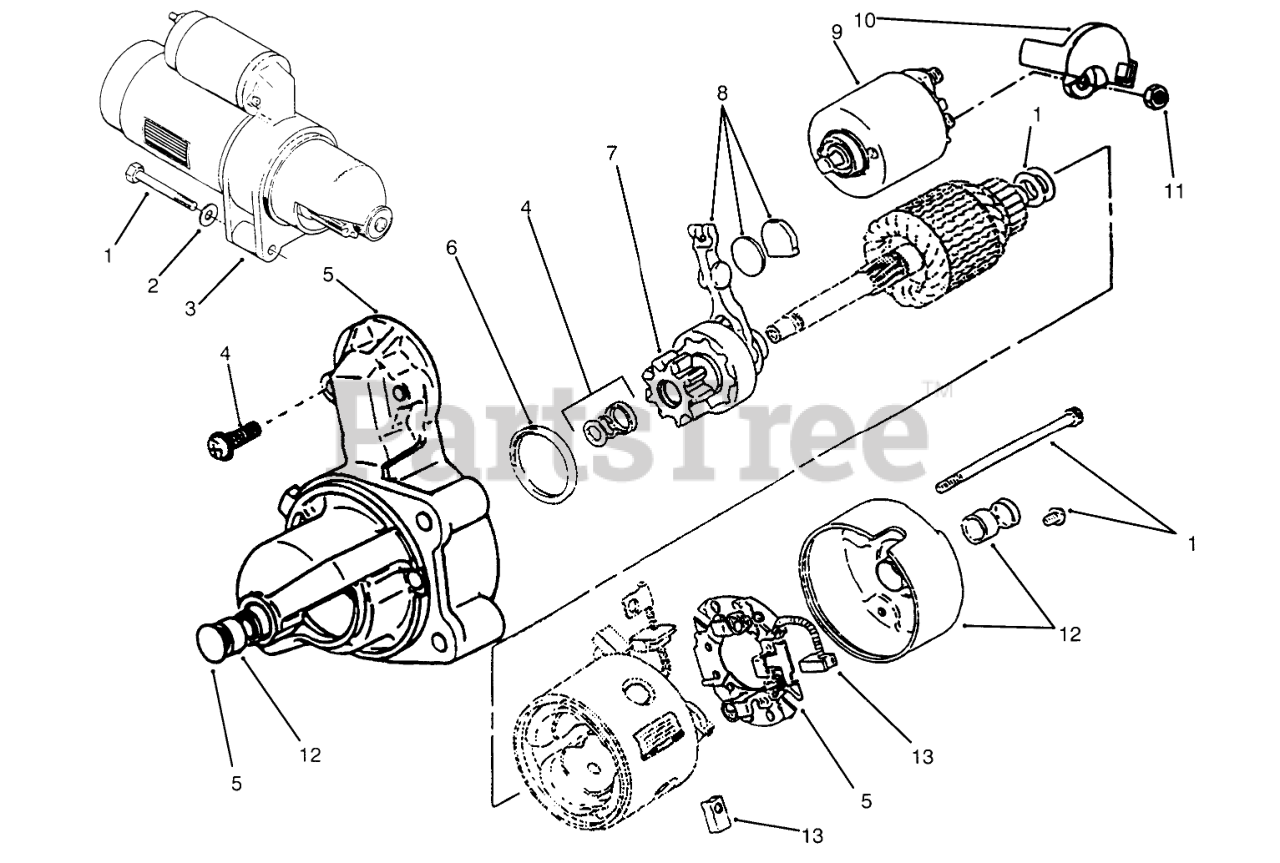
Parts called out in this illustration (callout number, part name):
1	SCREW
2	WASHER
3	STARTER
4	Kit-Hardware, Starter (Includes (2) Solenoid Mtg Screws, 2 Thru Bolts, Armature Shims, Pinion Collar, & Retaining Ring)
5	Kit-Mounting Bracket (Incl. Ref. #13)
6	DUST-SEAL KIT
7	Assembly-Clutch, Starter (Includes Pinion Gear)
8	Kit-Shift Lever, Starter (Includes Lever, Wear Plate & Rubber Plug)
9	Kit-Solenoid, Starter (Includes Solenoid & Spring Plunger)
10	Cap-Starter Solenoid
11	WASHER-FLAT
12	Kit-Bushing, Starter (Incl. Rear Cap with Bushing & Front Bushing)
13	Kit-Brush, Starter (Includes (2) Negative & (1) Positive Brushes)
